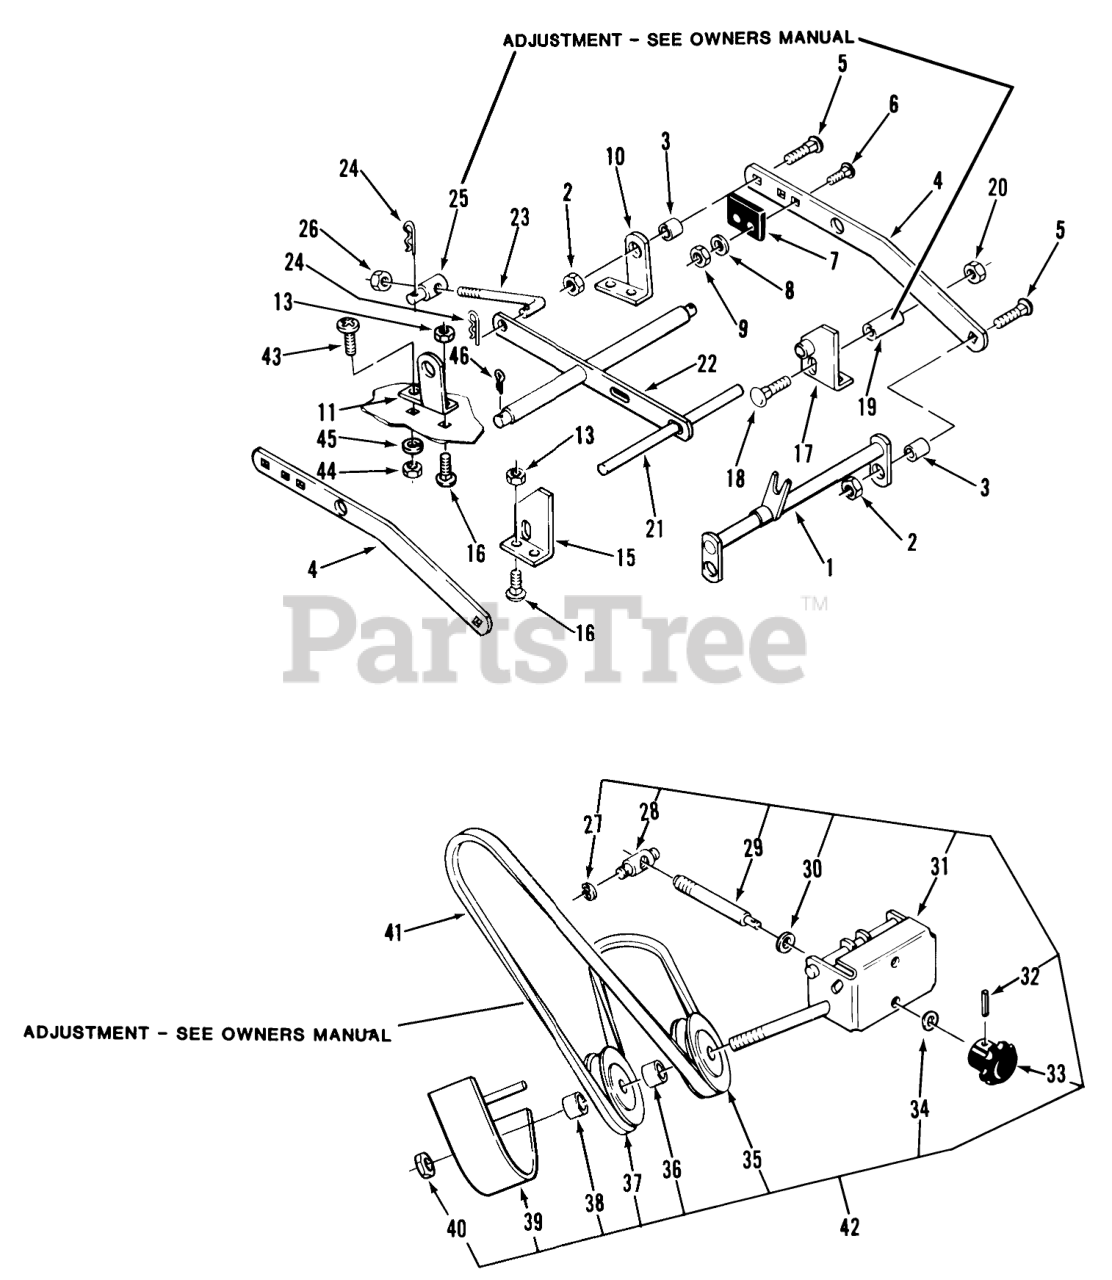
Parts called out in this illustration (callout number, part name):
1	Hitch
2	LOCKNUT-FLANGE
3	SPACER
4	Bar Draft
5	Bolt
6	Bolt-Carriage
7	BUMPER
8	Collar
9	Nut
10	LH Rear Bracket
11	Rear Bracket RH
13	Nut
15	Front Bracket RH
16	Bolt-Carriage
17	Front Bracket LH
18	CARRIAGE BOLT -4
20	Nut
21	Front Shaft
22	Leveler
23	ROD-LEVEL ADJUST
24	Hairpin
25	TRUNNION-LIFT
26	NUT
27	RING-RETAINING
28	TRUNNION-DOUBLE
29	ROD ADJ
30	Washer
31	Front Support
32	PIN-ROLL
33	KNOB-ADJUSTMENT
34	WASHER-SPRING
35	Pulley-V
36	SPACER
37	PULLEY-FLAT IDLER
38	SPACER-OUTER
39	Belt Cover
40	Nut
41	V-BELT
42	ASM-SUPPORT,IDLER
43	PAN HEAD SCREW-4
44	Nut
45	LOCKWASHER
46	Cotter Pin
